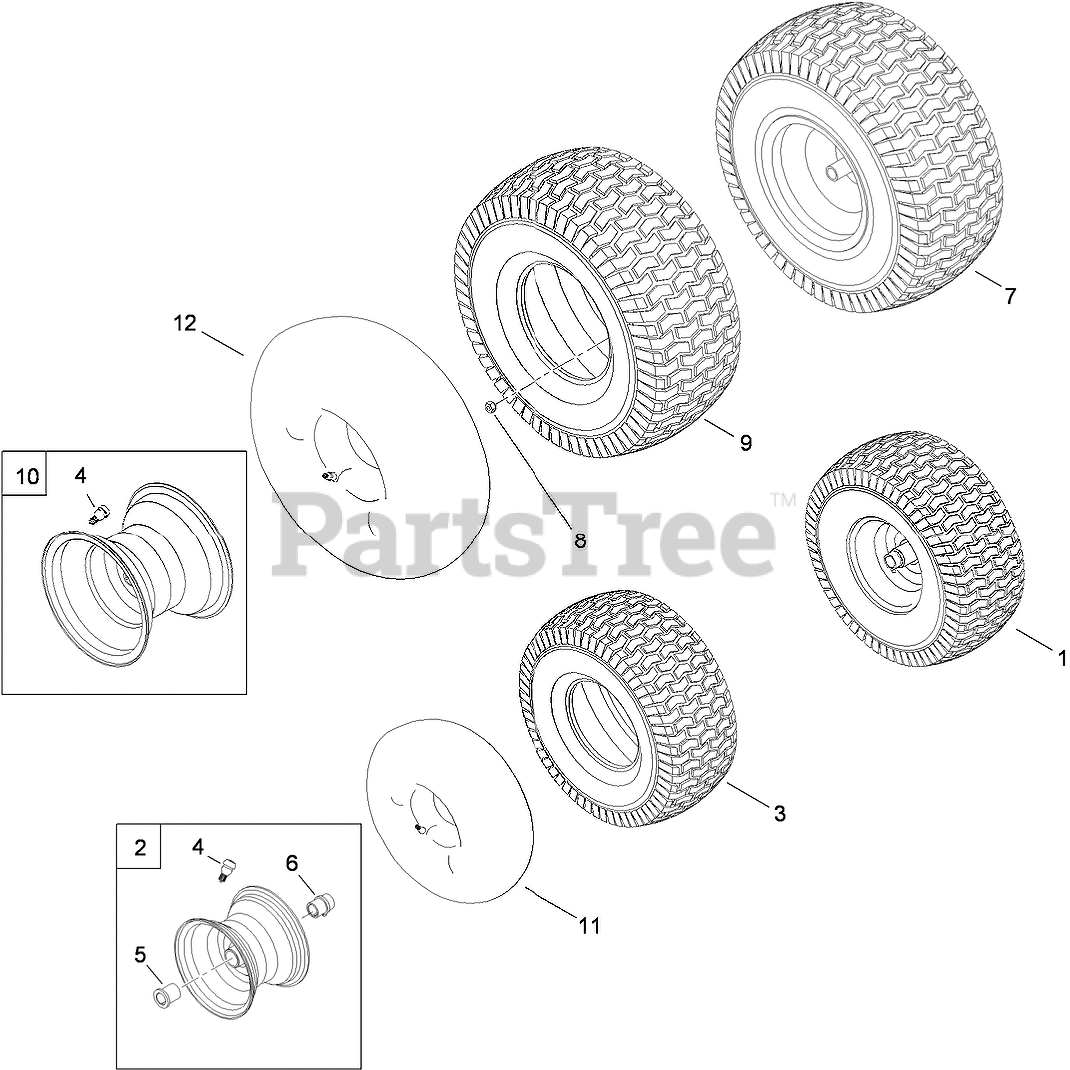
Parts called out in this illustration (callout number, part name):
1	TIRE AND WHEEL ASM
2	RIM ASM
4	VALVE-AIR, TUBELESS
5	BEARING-FLANGE
6	BEARING-FLANGE (W/ZERK)
7	WHEEL ASM
8	NUT-LUG
9	TIRE-TURF
10	RIM ASM
11	TUBE-INNER
